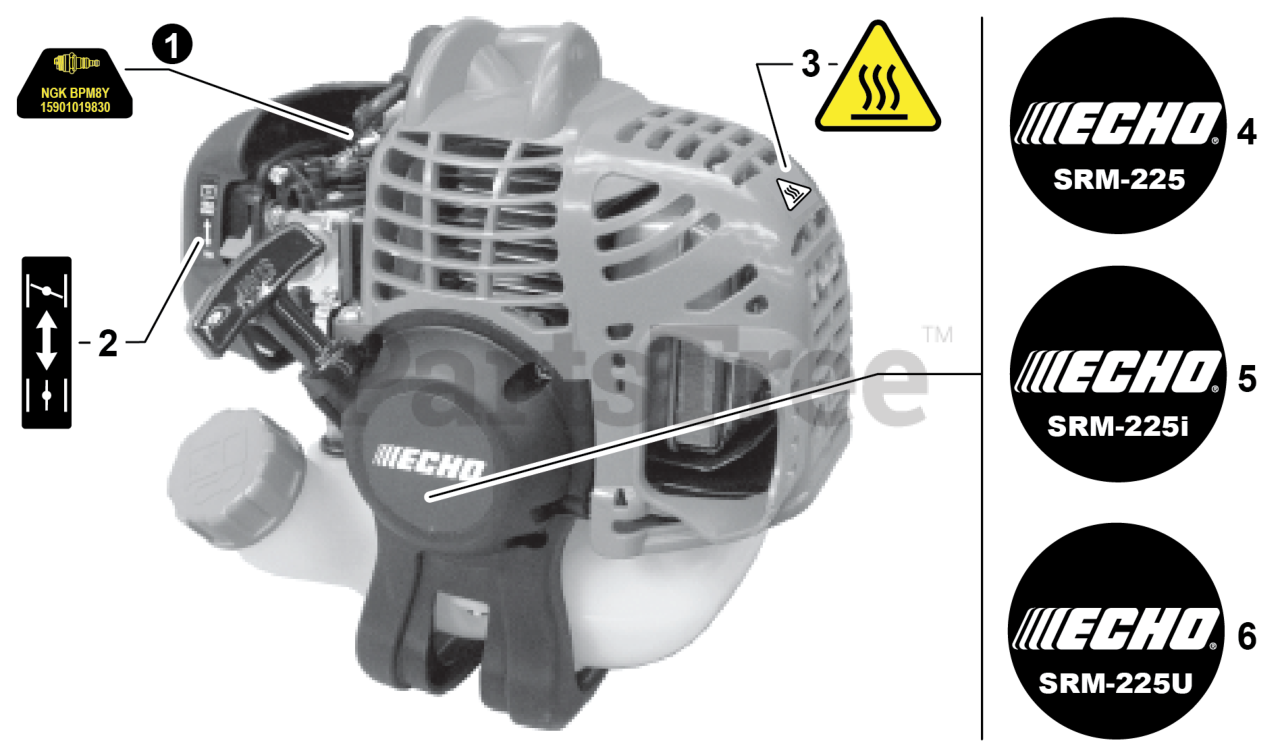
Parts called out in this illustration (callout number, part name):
1	LABEL - SPARK PLUG - BPM8Y
2	LABEL - CHOKE
3	LABEL - CAUTION - HOT
4	LABEL - STARTER - SRM-225
5	LABEL - STARTER - SRM-225I
6	LABEL - STARTER - SRM-225U
